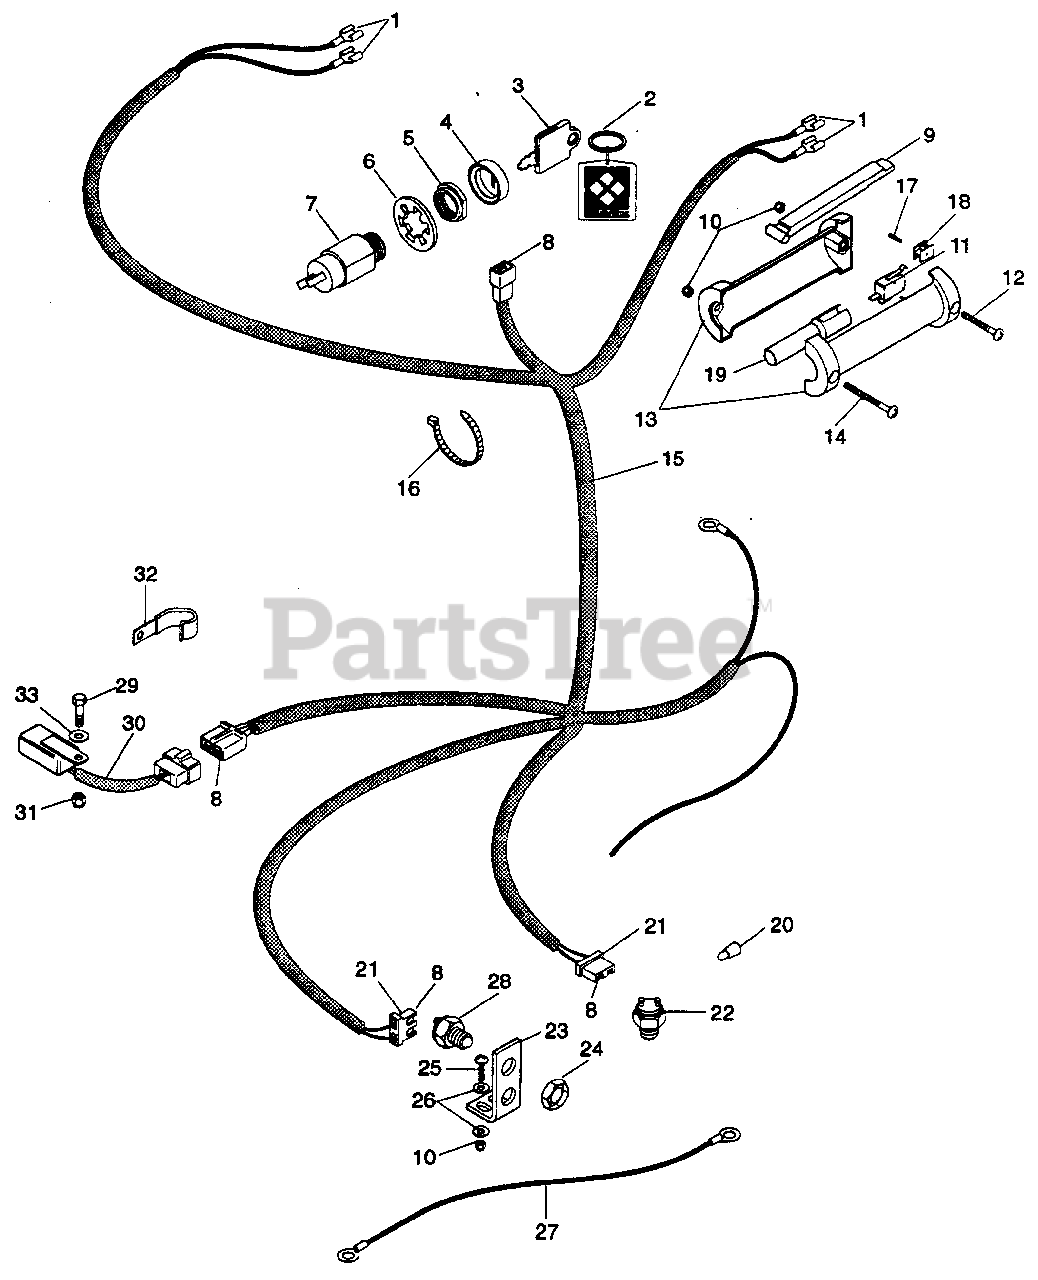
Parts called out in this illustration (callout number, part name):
1	TERMINAL, FEMALE
2	KEY CHAIN
3	IGNITION SWITCH KEY
4	CAP-IGNITION SWITCH
5	NUT-PANEL .625-32 GRECO
6	WSHR-LOCK .625 INT TOOTH
7	KEY SWITCH ASSEMBLY
8	TERMINAL
9	LVR
10	NUT-LK 10-24 NY PL
11	SWITCH
12	SCR-MCH 10-24 X 1.50 PDHCR
13	HANDLE, L.H. & R.H.
14	SCR-MCH 10-24 X 1.50 PHDCR
15	HMS, WIRING PRO RECOIL
16	TIE WRAP, BLACK
17	PIN-ROLL .094 X .750
18	HOLDER, SWITCH
19	INSERT, HANDLEBAR(PROS)
20	NUT-CNCTR
21	CONN, 2-WIRE SWITCH
22	SWITCH-NEUTRAL START N.C.
23	BRKT, INTERLOCK SWITCH
24	NUT-STAMPED .56-18
25	SCR-MCH 10-24 X .750 PHD
26	WSHR-FL-STL .188 X .438 X .049
27	WIRE, GROUND
28	SWITCH-NUETRAL START N.O.
29	BLT-HEX .25-20 X .75 PL GR 5
30	MODULE, INTERLOCK RECOIL
31	NUT-LK-NYL .250-20 PL
32	J-CLAMP
33	WSHR-FL-STL .344 X .688 X .065 PL
